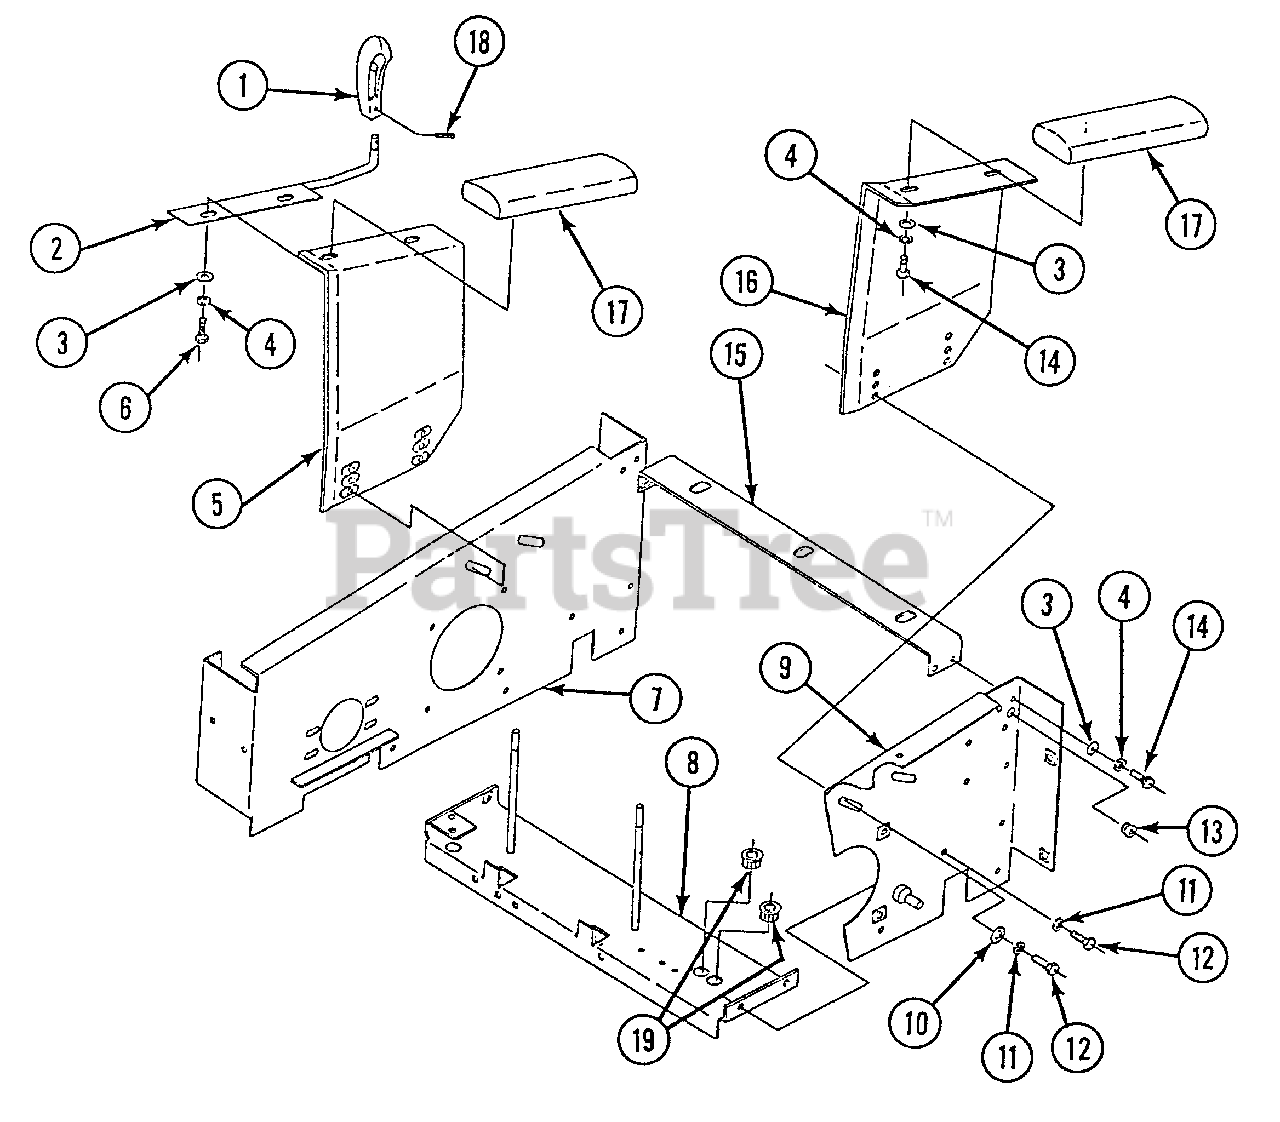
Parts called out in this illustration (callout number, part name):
1	HANDLE
2	SECURITY HANDLE WLDT.
3	WASHER, 5/16 STD. FLAT
4	LOCKWASHER, 5/16 SPLIT SPRING
5	ADJUSTABLE ARM REST, LEFT
6	CAPSCREW, HEX. 5/16-18 X 1
7	SIDE PLATE WLDT. LEFT
8	BATTERY MOUNT WLDT.
9	SIDE PLATE WLDT. RIGHT
10	WASHER, 3/8 STD. FLAT
11	LOCKWASHER, 3/8 SPLIT SPRING
12	CAPSCREW, 3/8-16 X 3/4 GR. 5
13	GROMMET
14	CAPSCREW, 5/16-18 X 3/4
15	SEAT MOUNT BRKT.
16	ADJUSTABLE ARM REST, RIGHT
17	ARM REST PAD ASSEMBLY
18	ROLL PIN, 3/16 X 1
19	BUSHING, PLASTIC, WIRE PROTECTOR
